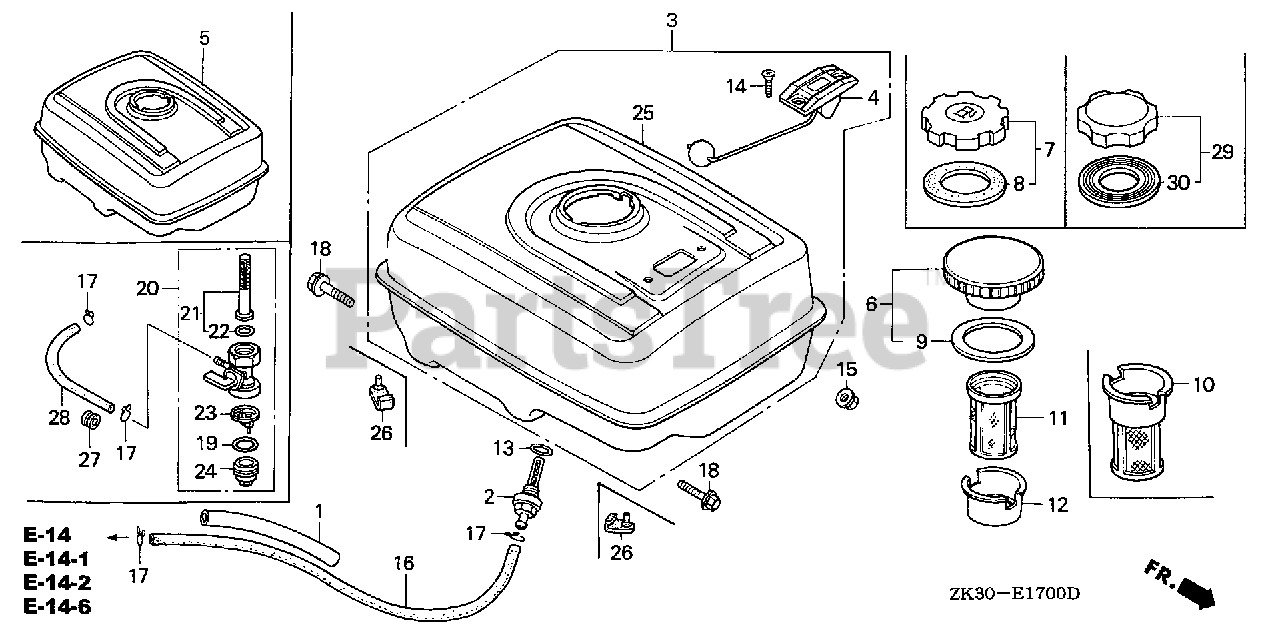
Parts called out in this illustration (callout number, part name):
1	RUBBER, SUPPORTER (107MM)
2	JOINT, FUEL TANK (NOT AVAILABLE)
2	JOINT, FUEL TANK
5	TANK, FUEL *NH31* (MCKINLEY WHITE)
7	CAP, FUEL FILLER (BLACK)
8	GASKET, FUEL FILLER CAP (39X58X3)
10	FILTER, FUEL
13	O-RING (14MM) (ARAI)
13	O-RING (14MM) (NOK)
15	NUT, FLANGE (8MM)
16	BULK HOSE, FUEL (4.5X3000) (4.5X235)
17	CLIP, TUBE (B8)
18	BOLT, FLANGE (8X25)
29	CAP, FUEL FILLER (CHROME PLATED)
30	GASKET, FUEL FILLER CAP (39X62X3) (TOUYOUSYA)
